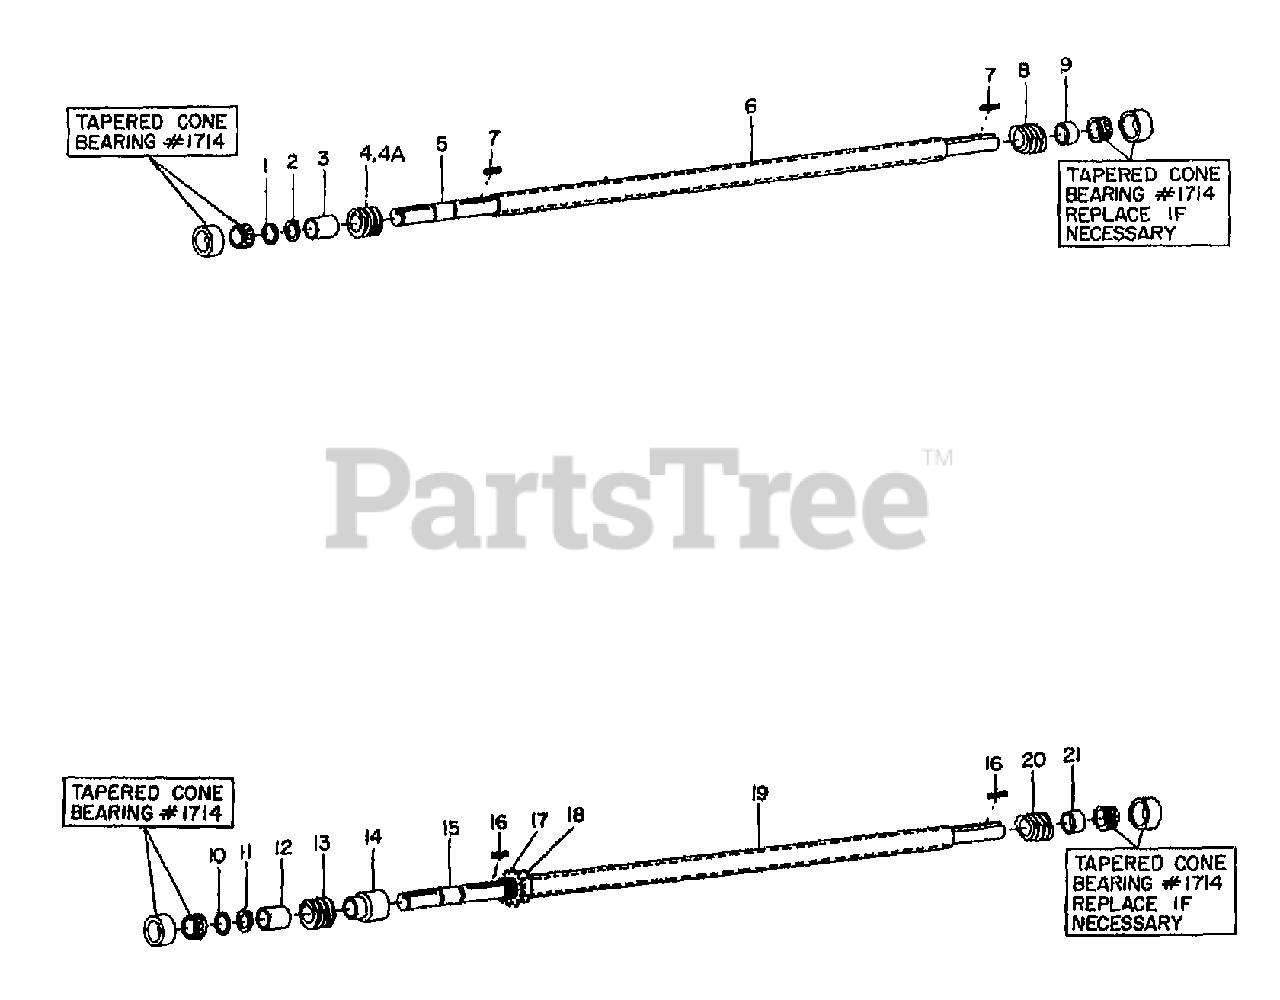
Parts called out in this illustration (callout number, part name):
1	SHIM-1.0X.7656X.062
2	RING-RETAIN EXT .707 ID
3	SPACER-1X.76X1.25
4	WORM-1.25 PD .26 LEAD
4A	GEAR-WORM 1.25 PD .62 LEAD
5	DRIVESHAFT-MACH
6	SLEEVE-WORM SPACER
7	KEY-.188 SQX1.0
8	WORM-1.25 PD .62 LEAD
9	SPACER-1X.76X.54
10	SHIM-1.0X.7656X.062
11	RING-RETAIN EXT .707 ID
12	SPACER-1X.76X1.25
13	GEAR-WORM 1.25 PD .62 LEAD
14	SPACER-1.25X(VAR)X1.5
15	DRIVESHAFT-MACH
16	KEY-.188 SQX1.0
17	SPACER SLEEVE
18	NUT 1.0-14 ADJ
19	TUBING-MACH
20	WORM-1.25 PD .62 LEAD
21	SPACER-1X.76X.54
